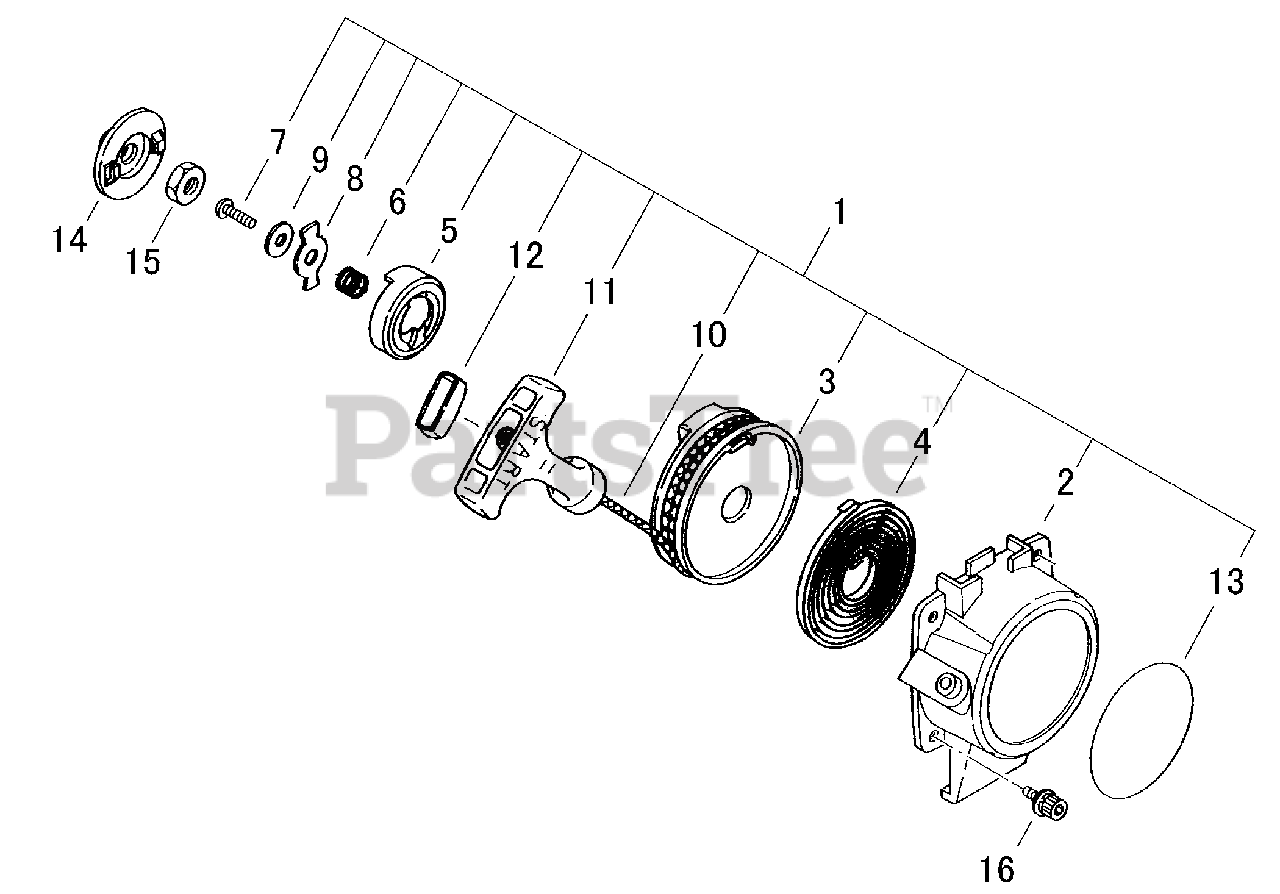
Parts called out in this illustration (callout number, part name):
2	CASE, STARTER
3	REEL, ROPE
4	SPRING, REWIND
5	CATCHER, PAWL
6	SPRING
6-1	STARTER ASSY
8	RETAINER
9	WASHER
10	ROPE, STARTER
11	GRIP, STARTER
12	RETAINER, ROPE
13	RECOIL LABEL
14	REEL, ROPE
15	NUT - 8
16	SCREW - 4X12
